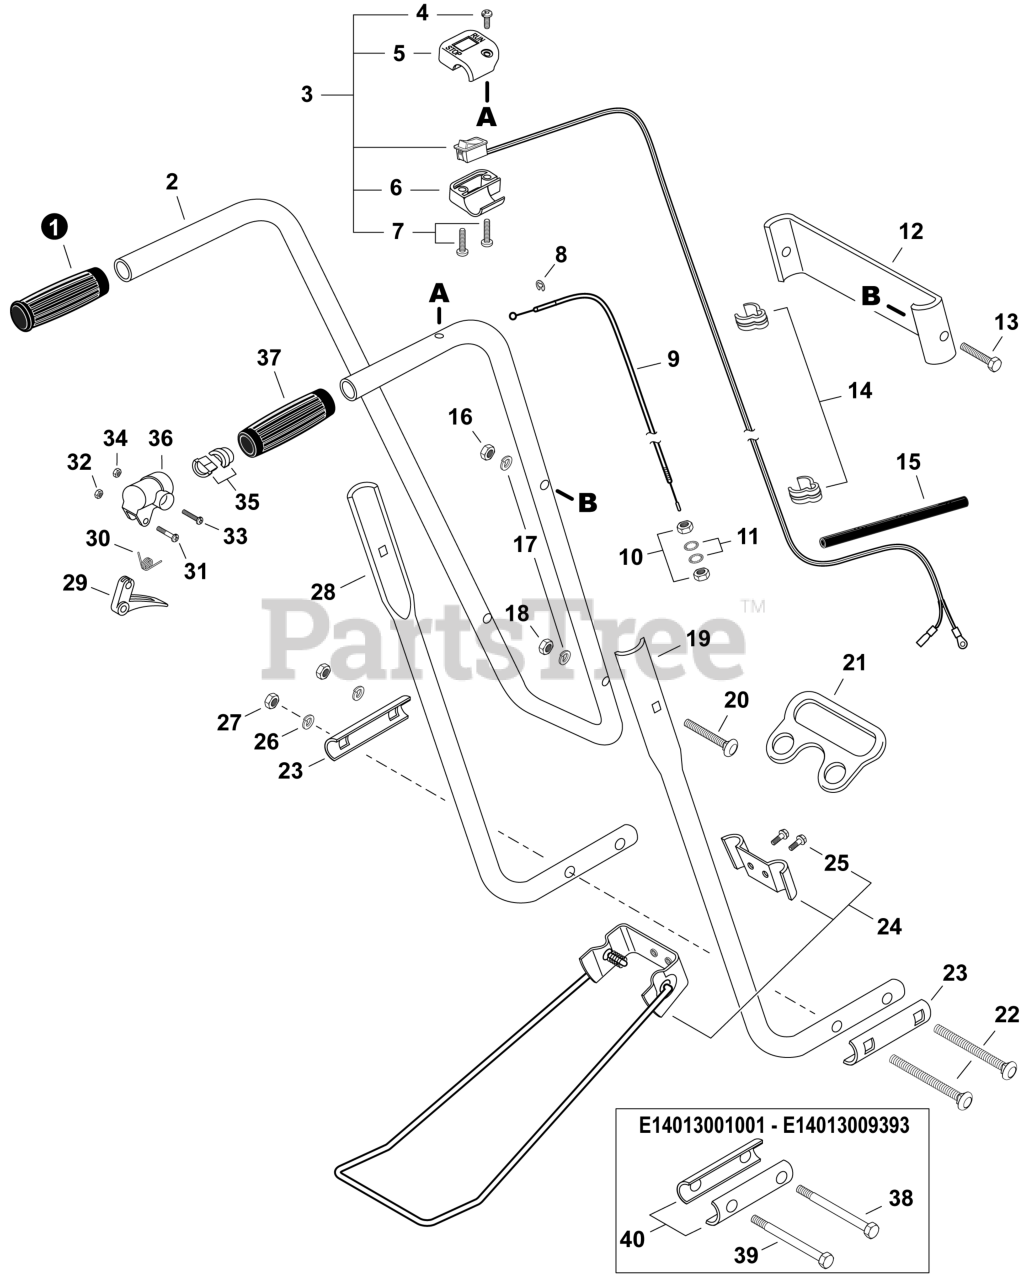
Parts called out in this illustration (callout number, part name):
1	GRIP, HANDLE
2	HANDLE, UPPER
3	SWITCH KIT, ON-OFF
4	SCREW 5x10
5	COVER, SWITCH
6	CASE, SWITCH
9	CABLE, THROTTLE
11	WASHER, LOCK 6 MM
12	SUPPORT, HANDLE
13	BOLT 1/4"x1-1/4"
16	NUT, LOCK 1/4
17	WASHER, SPRING
19	HANDLE, LOWER - RIGHT
21	HANDLE, FRONT
22	BOLT 1/4"-20x3-1/4"
23	PLATE, EYE
24	KICK STAND KIT
25	BOLT 6x12
26	WASHER, SPRING
27	NUT, LOCK 1/4
28	HANDLE, LOWER - LEFT
29	TRIGGER, THROTTLE
33	SCREW 5x25
34	NUT, LOCK M5
35	HOLDER, CABLE
36	BRACKET, TRIGGER
37	GRIP, HANDLE
38	BOLT 1/4"x3"
39	BOLT 1/4"-20x3-1/4"
40	PLATE, EYE
